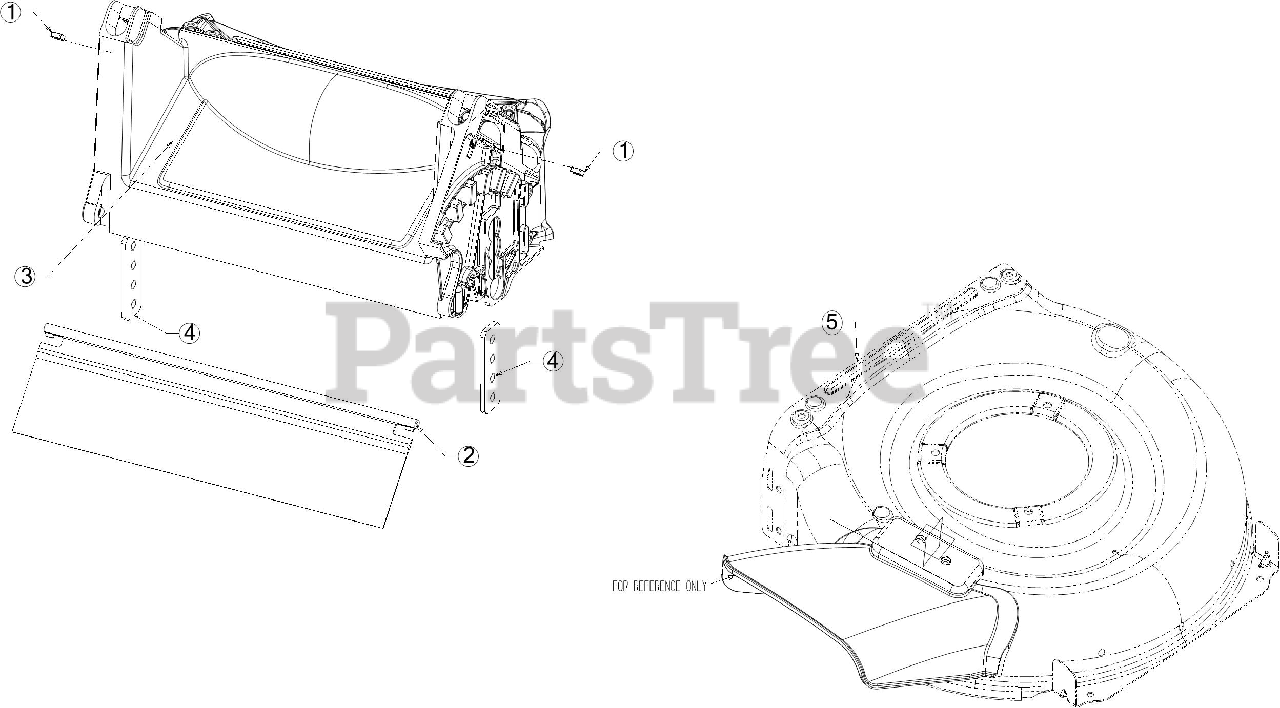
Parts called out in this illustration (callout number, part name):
1	SQUARE NUT 1/4-20
2	TRAILSHIELD
5	21" DECK (3N1)
